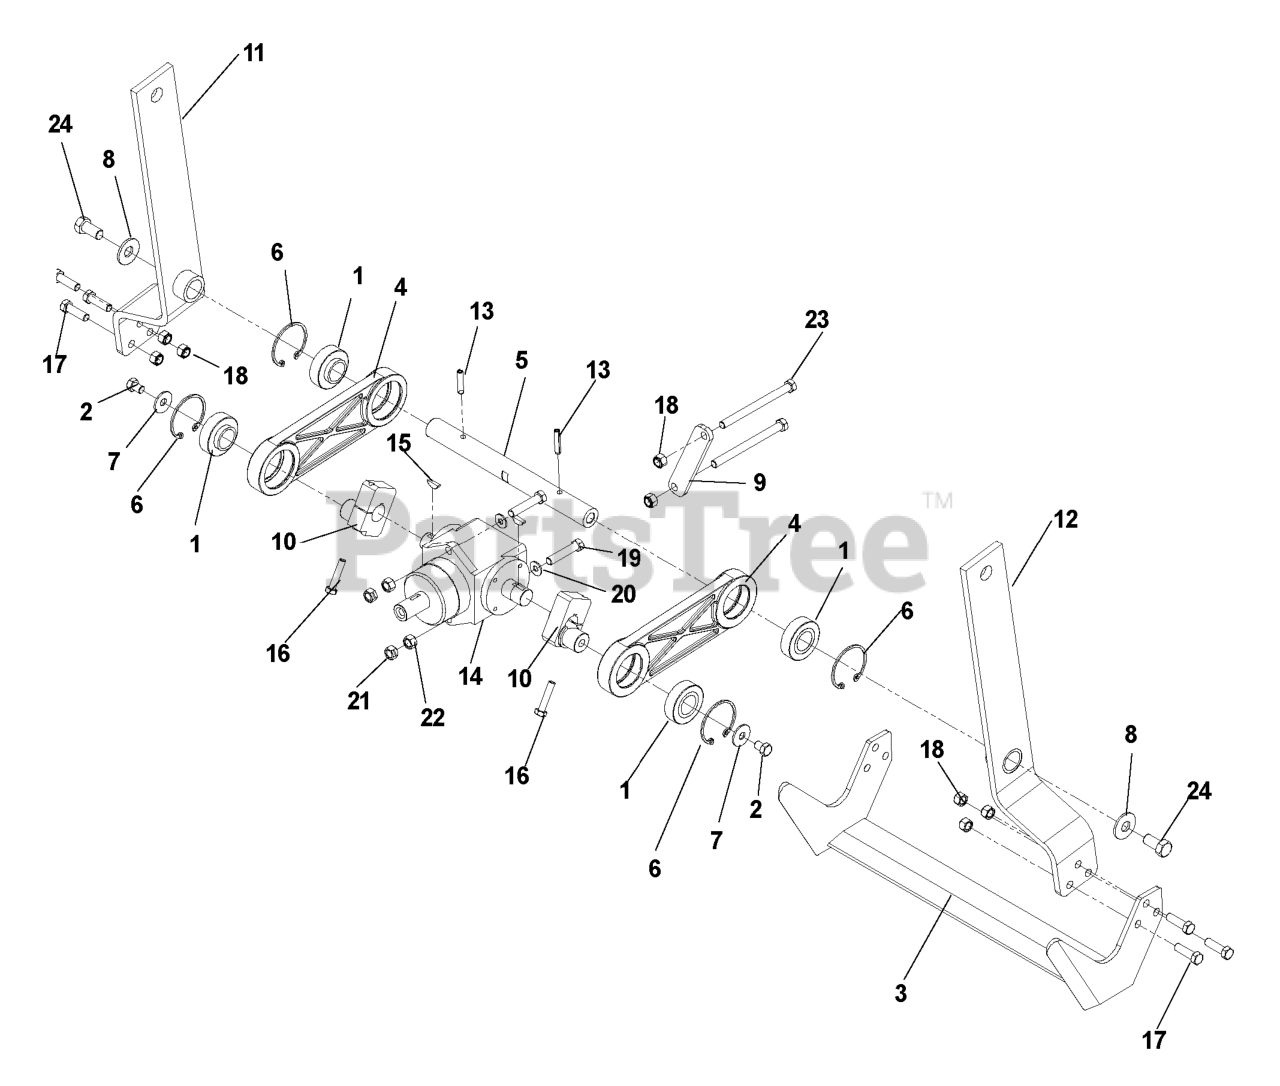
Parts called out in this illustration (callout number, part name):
1	BEARING
2	BOLT .375 X .5
3	KIT CUTTING BLADE 18" SOD CUT
4	LINK - CONNECTING
5	SHAFT - BLADE ARM
6	SNAP RING 52MM
7	SPRING WASHER - .38
8	SPRING WASHER - .50
9	STRAP T-BOX BLACK
11	BLADE ARM R.H., BLACK
12	BLADE ARM L.H., BLACK
13	SPIRAL PIN 1/4 DIA X 1.25
14	GEARBOX RIGHT ANGLE "T" DRIVE
15	KEY, #9 WOODRUFF
16	CAPSCREW 5/16 X 1/1/2 HEX HEAD
17	HCS 3/8C X 1 1/4 GR5
18	NUT 3/8-16 NYLOC
19	HCS 3/8-24
20	WASHER 3/8 SAE FLAT
22	NUT 3/8F CENTERLOCK
23	HCS 3/8C X 4 1/2
24	HHCS 1/2-13 X 1
